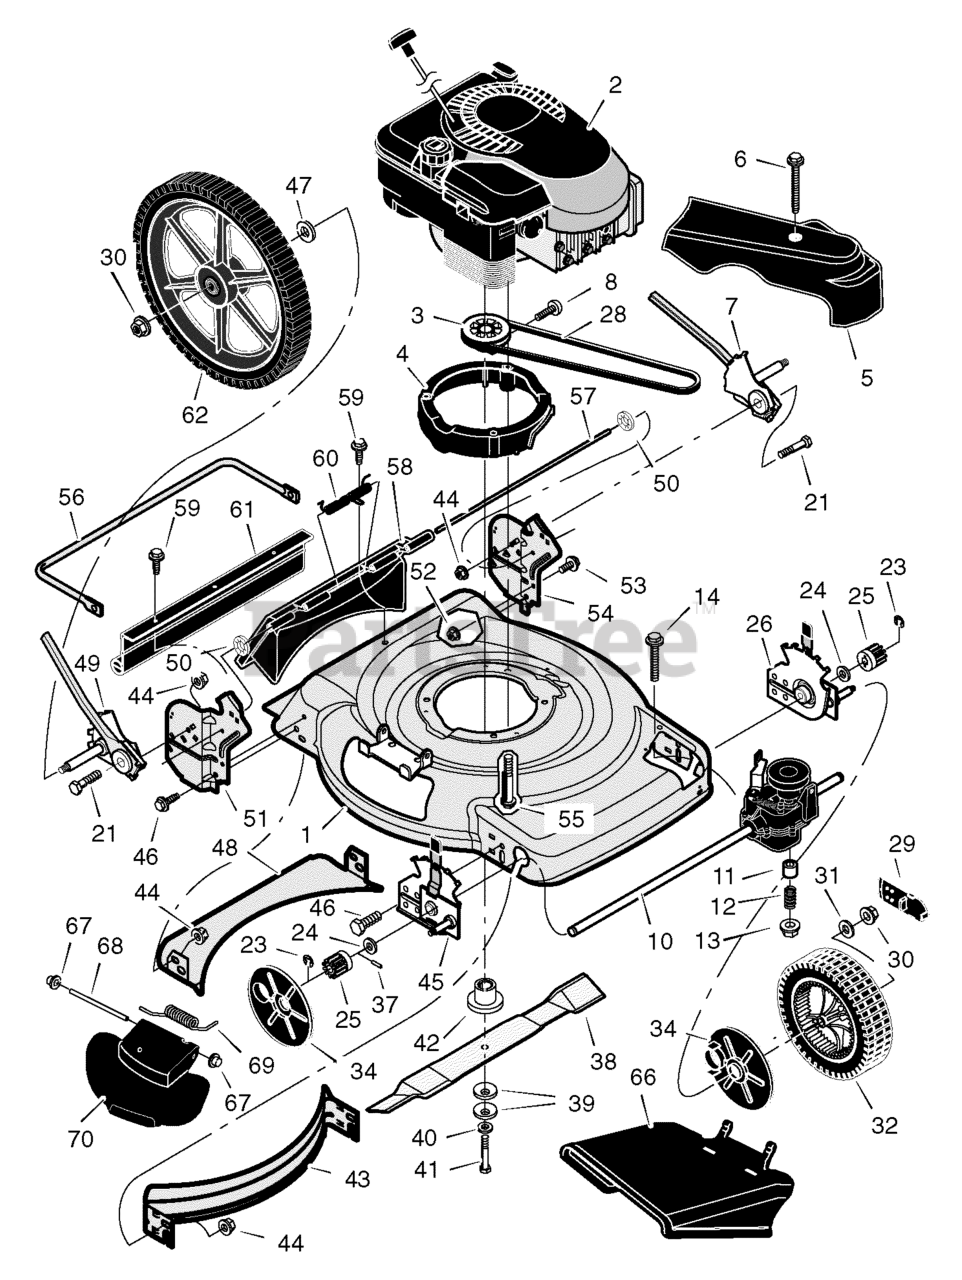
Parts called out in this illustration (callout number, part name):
1	Housing
2	Engine *
3	Pulley, Drive
4	Spacer, Engine
5	Cover, Belt (Black)
5	Cover, Belt (Gray)
7	Adjuster, Left Rear Height
10	Transmission *
11	Spacer
12	Spring, Compression
13	Nut
14	Bolt
23	E-Ring
24	Washer
25	Gear, Pinion
26	Adjuster, Left Front Height
29	Cap, Hub
30	Nut, Flange
31	Washer
32	Wheel & Tire, Front
34	Cover, Dust
37	Pin, Drive
39	Washer, Belleville
40	Washer
42	Adapter, Blade
43	Baffle, Front
44	Nut, Flange
45	Adjuster, Right Front Height
46	Bolt
47	Washer
48	Baffle, Rear
49	Adjuster, Right Rear Height
50	Retainer, Push
51	Bracket, Right Handle
52	Nut, Flange
53	Bolt
54	Bracket, Left Handle
55	Bolt, Engine
57	Rod, Pivot
58	Door, Rear (Black)
58	Door, Rear (Gray)
60	Spring
61	Guard, Rear
62	Wheel & Tire, Rear
66	Deflector, Chute (Black)
66	Deflector, Chute (Gray)
67	Push On Cap
68	Rod, Pivot
69	Spring, Torsion
70	Cover, Mulch (Black)
70	Cover, Mulch (Gray)
